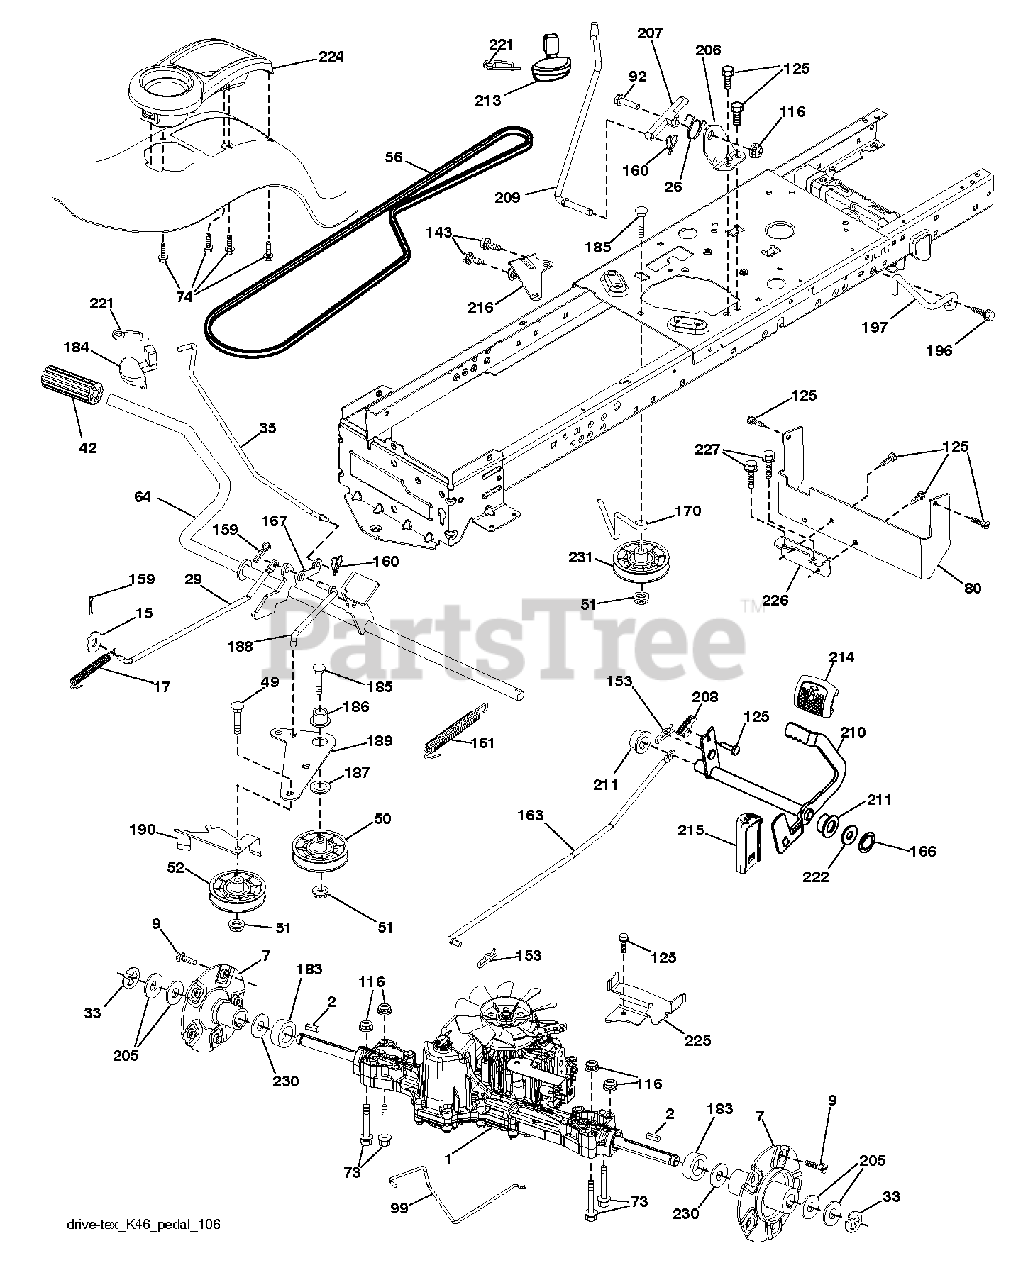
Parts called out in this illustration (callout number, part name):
2	KEY.SQUARE.187X2.500
7	HUB.ASM.WHEEL.REAR.22"
9	HUB BOLT
17	SPRING.BRAKE.K46.GREEN
26	SPRING.RETURN.CRUISE
29	ROD.BRAKE.K46
33	E-RING LT
35	ROD.BRAKE.PARKING.LT.T
49	BOLT
50	IDLER.FLAT.910.OFFSET
51	NUT LOCK FLG 3/8-16 UNC
52	IDLER.V-GROOVE.910.OFFSET
56	V-BELT.MOWER.92.40.42/K46
64	SHAFT.ASM.PEDAL.BRK.CNTR
74	SCREW.HI-LO.CONSOLE
80	STRAP.TORQUE.K46.K57R.TT
92	BOLT
99	ROD.SPRING.BYPASS.K46.LT.Z
116	NUT LOCK HEX FLANGE 5/16-18
125	SCREW
143	SCREW LT
159	COTTER PIN
160	RETAINER CLIP
161	SPRING, RETURN LT
163	ROD.CONTROL.K57R.K46
166	NUT.PUSH.625
167	LATCH.BRAKE.SPRING
170	KEEPER.CENTER SPAN.1.688
183	SPACER.SPLIT.800X.350
184	HANDLE.PARKING.BRAKE.LTTEX.667
186	SPACER.RETAINER
187	WASHER 12/32X2X10GA
188	LINK.CLUTCH.GROUND.DRIVE
189	BELLCRANK.GROUND.DRIVE.TEX.
190	KEEPER.BELLCRANK.DRIVE
196	SCREW 3/8-16X1
197	BRKT.ANIT-ROTATION.CLUTCH
206	BRACKET.MOUNT.CRUISE.LATCH
207	LATCH.CONTROL.CRUISE
208	GEAR.SECTOR.CONTROL.CR
210	ROCKER.ASM.PEDAL.CONTR
211	BEARING.NYLON
213	HANDLE.CONTROL.CRUISE.ELTE
214	PEDAL.FORWARD.PAD.TEX
215	PEDAL.REVERSE.TEX.GT.4
216	BRACKET.PULLEY.IDLER.W/TEX
221	RETAINER.SPRING.CLIP.H
222	WASHER 21/32 X 1-1/4 X 10 GA.
224	CONSOLE.TOOLBOX.PCH.ERGO.BLACK
225	KEEPER.BELT.TRANSAXLE.K46
226	BRACKET.MOUNT.TORQUE.K46.TLT
227	Screw, Lt
230	WASHER.HARDENED
231	IDLER.V-GROOVE.1.688.OFFSET
